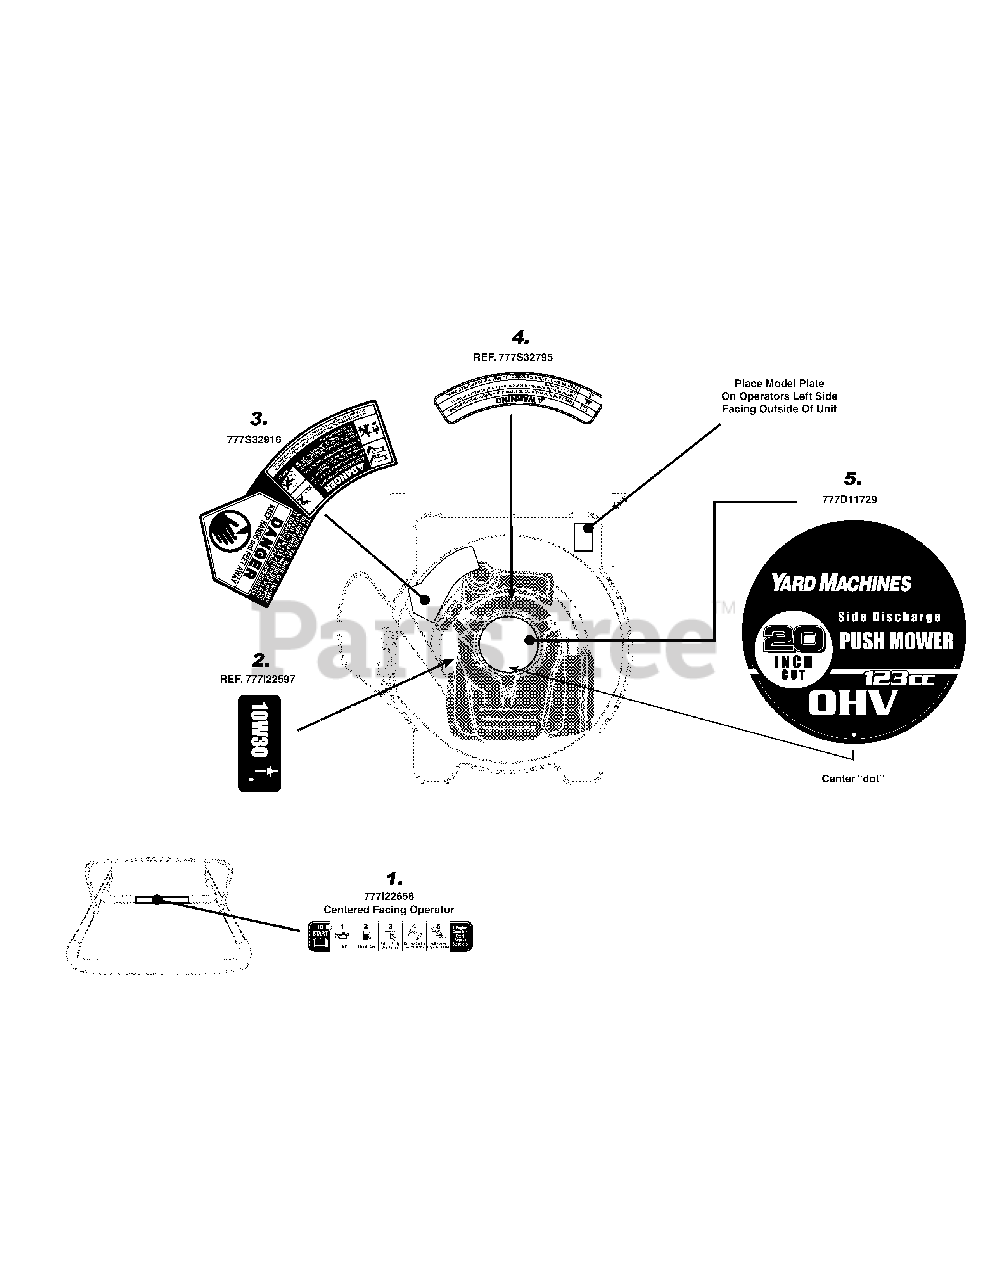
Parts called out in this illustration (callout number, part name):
1	LABEL-MOWER HANDLE:START INST
2	LABEL:MOWER SHROUD
3	LABEL-MOWER DECK SAFETY
4	LABEL-WARNING
5	LABEL-MOWER SHROUD
